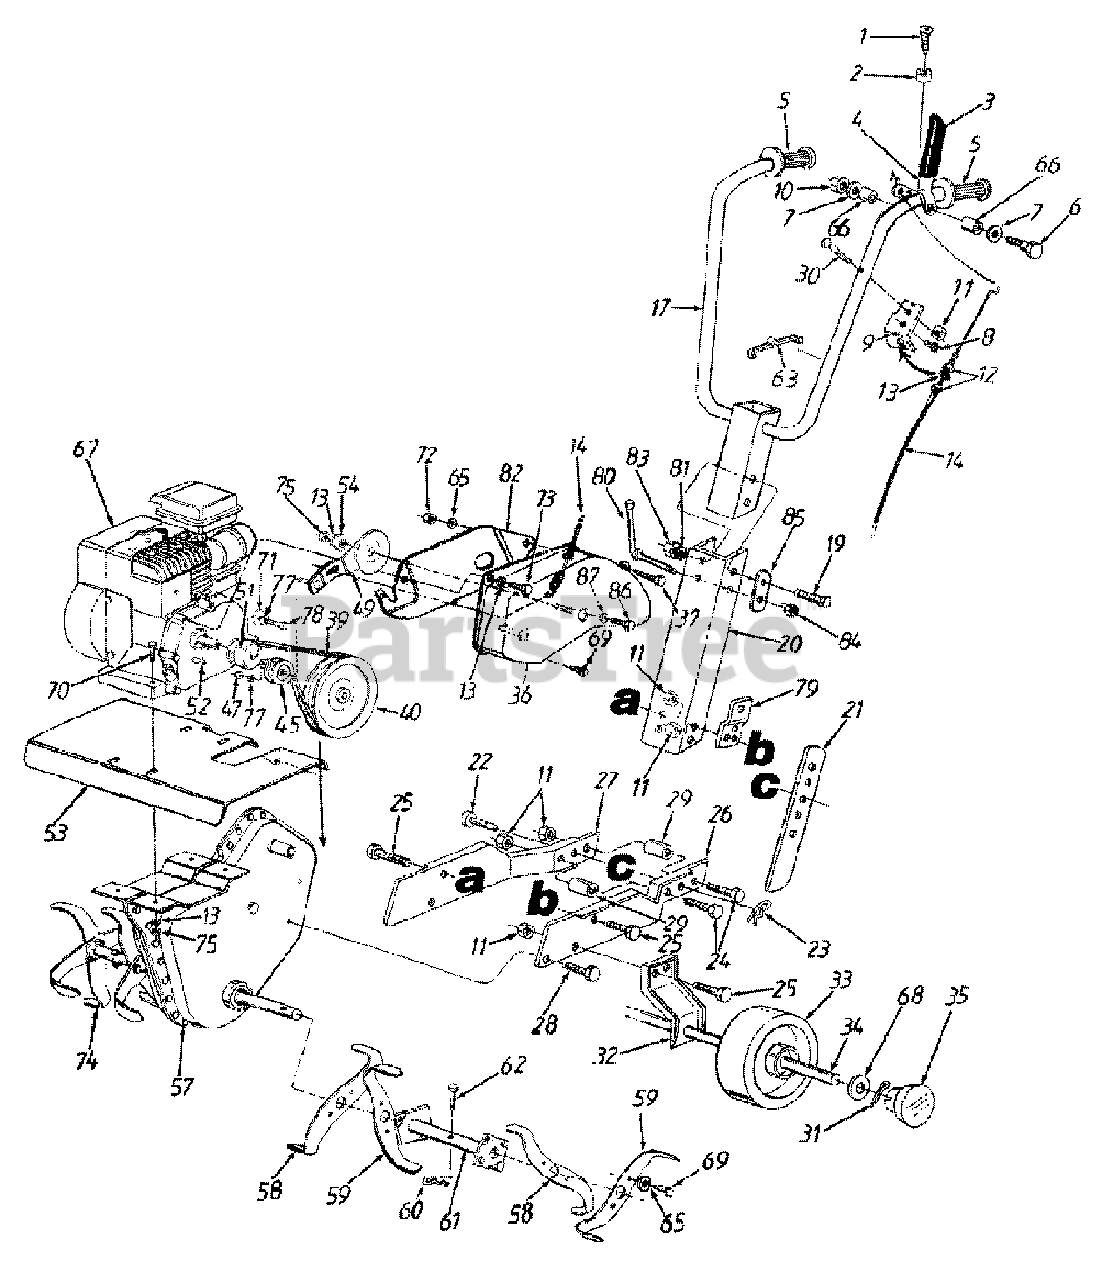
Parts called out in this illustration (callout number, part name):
1	Tap Scr. #10 x 1/2" Lg.
2	Rubber Bumper
3	Vinyl Grip
4	Clutch Lever Ass'y.
5	Handle Grip
6	Hex Bolt 1/4-20 x 2" Lg.
7	Fl-Wash. 1/4" I.D.
8	Hex Tap Scr. 1/4-20 x 1/2" Lg.
9	Cable Bracket
10	Lock Nut 1/4-20 Thd.
11	Lock Nut 5/16-18 Thd.
12	Hex Jam Nut 5/16-24 Thd.
13	L-Wash. 5/16" I.D.
14	Clutch Control Cable
17	Handle Ass'y.
19	Hex Bolt 3/8-16 x 2.75
20	Handle Channel - Frame
23	Hairpin Cotter
24	Hex Bolt 5/16-18 x 1" Lg.
25	Hex Bolt 5/16-18 x 5/8" Lg.
26	L.H. Frame Half
27	R.H. Frame Half
28	Hex Tap. Scr. 5/16-18 x 1/2" Lg
29	Spacer
30	Hex Bolt 5/16-18 x 1-1/4" Lg.
31	Cotter Pin
32	Wheel Bracket
33	Wheel - 6"
34	Axle - Wheel
35	Hub Cap
36	Belt Cover
37	Hex Bolt 1/4-20 x 5/8" Lg.
39	V-Belt
40	Pulley - Chain Case
45	Flat Idler Pulley
47	Hex Jam L-Nut 3/8-24 Thd.
49	Idler Arm Ass'y.
51	Engine Pulley
52	Square Key 3/16" x .75" Lg.
53	Tine Shield
54	Washer - Bushing
57	Chain Case Ass'y. Comp.
58	R.H. Tine Blade
59	L.H. Tine Blade
60	Hairpin Cotter
61	Adapter Ass'y. - Tine
62	Clevis Pin
63	Cable Tie - Plastic
65	L-Wash. 1/4" I.D.
66	Spacer
67	Engine
68	Fl-Wash. .406 I.D.
69	Tap Scr. 1/4-20 x 1/2" Lg.
70	Hex Bolt 3/8-16
71	Fl-Wash. 3/8" I.D. x 1" O.D.
72	Hex Nut 1/4-20 Thd.
73	Hex Bolt 5/16-24 x .5" Lg.
74	Tine Blade Ass'y. Comp.
75	Hex Nut 5/16-18 Thd.
77	L-Wash. 3/8" I.D.
78	Hex Bolt 3/8-24 x 1" Lg.
79	Belt Cover Bracket
80	Handle Adj. Crank
81	Fl-Wash. .385" I.D. x .87" O.D.
84	Hex Flange L-Nut 3/8-24 Thd.
85	Retainer Bracket
86	Hex Bolt 5/16-18 x .75" Lg.
87	Fl-Wash. .330 I.D.
